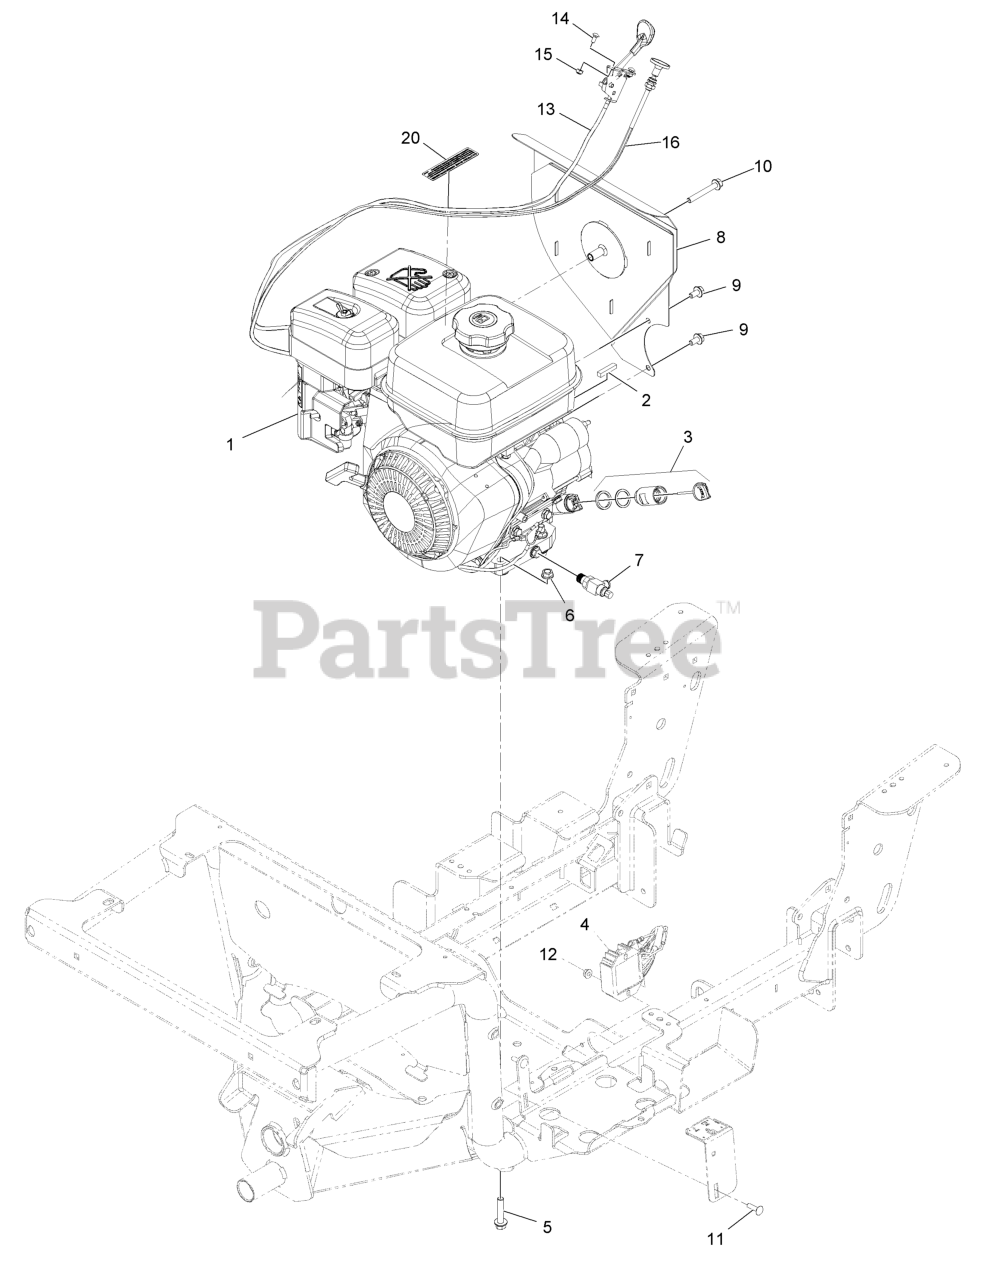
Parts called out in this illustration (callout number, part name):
2	KEY-CRANKSHAFT
3	EXTENDER-DIPSTICK
4	REGULATOR
5	SCREW-HHF
7	VALVE-OIL DRAIN
8	HEAT SHIELD ASM
9	SCREW-HHF, LOCK
10	SCREW-HHF
11	SCREW-CARR
13	CONTROL-THROTTLE
14	BOLT-CARR
15	NUT-LOCK, NI
16	CABLE-CHOKE, PUSH/PULL
20	DECAL-ARRESTER, SPARK
